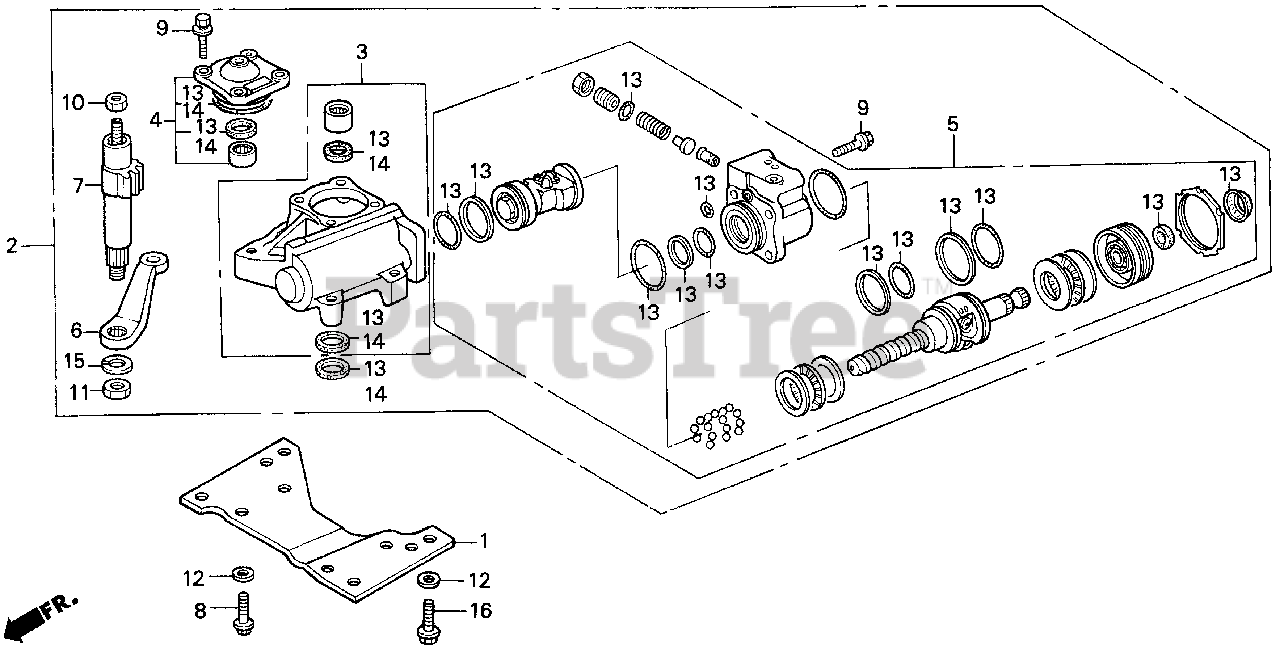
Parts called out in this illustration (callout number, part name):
1	PLATE, STEERING GEAR MOUNTING
2	GEAR ASSY., POWER STEERING
3	BOX ASSY., GEAR
4	COVER ASSY., SIDE
5	SCREW UNIT, BALL
6	ARM, PITMAN
7	SHAFT ASSY., CROSS
8	BOLT, SIDE MOUNTING (12MM)
9	BOLT-WASHER
10	NUT (12MM)
11	NUT (20MM)
12	WASHER, PLAIN (12MM)
13	SEAL KIT (GEAR BOX)
14	SEAL KIT (CROSS SHAFT)
15	WASHER, SPRING (20MM)
16	BOLT, FLANGE (12X32)
